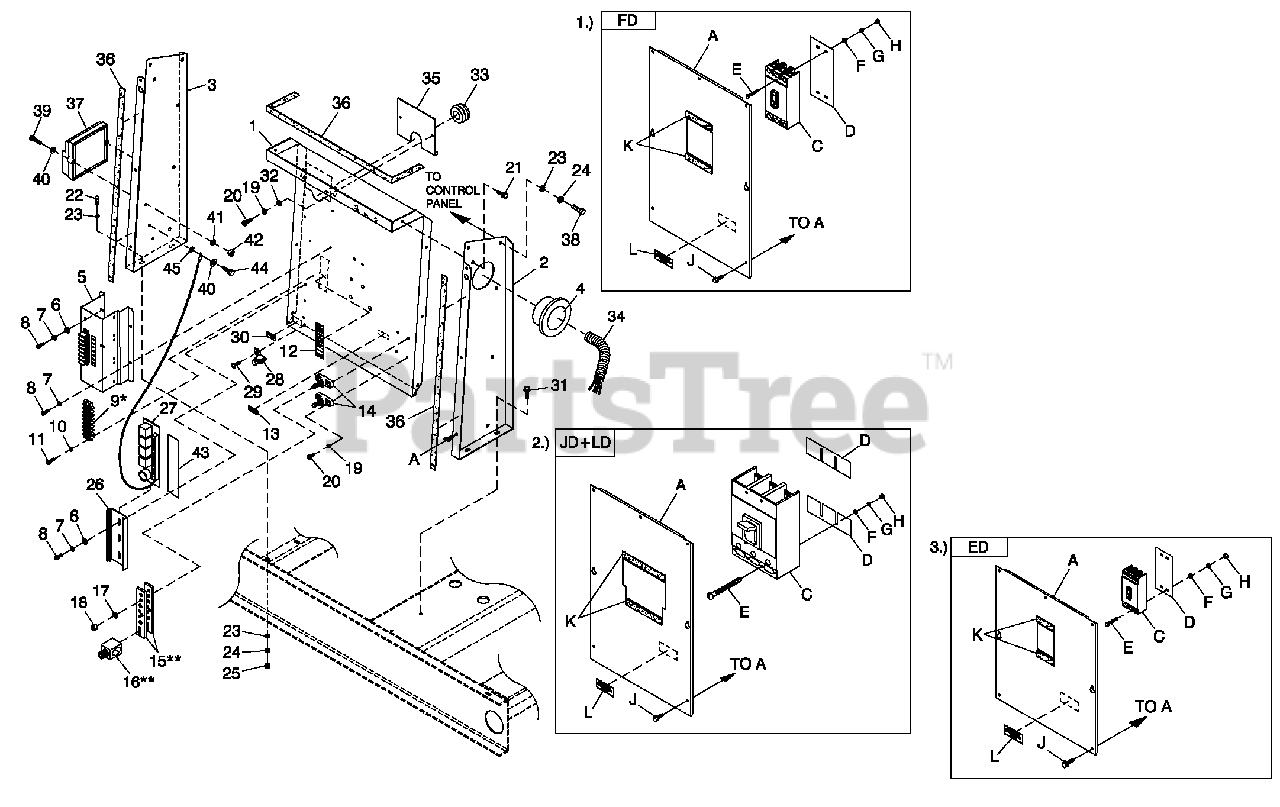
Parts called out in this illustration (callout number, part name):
1	PANEL CB CONN BOX
1	UL CIRCUIT BREAKER (FD)
2	STAND RH CONTROL
2	UL CIRCUIT BREAKER (JD+LD)
3	STAND LH CONTROL C5 GRBX
3	UL CIRCUIT BREAKER (ED)
4	BUSHING SNAP SB-2.5-31
5	INTERFACE 1PH 240V
6	WASHER FLAT M4
7	WASHER LOCK #8-M4
8	SCREW PHTT M4-0.7 X 10ZYC
9	BLOCK TERM 2 0 A 8 X 6 X 1100V
10	WASHER LOCK #6
11	SCREW PHTT #6-32 X 1/2 ZYC
12	DECAL CPL CUST CONN H CTRL
13	DECAL NEUTRAL
14	JUNCTION BLOCK 3/8-16
15	BUS BAR NEUTRAL BLOCK 390
16	LUG SLDLSS 600/250-1/0 X 1/4-28
17	WASHER LOCK 3/8
18	NUT HEX 3/8-16 STEEL
19	WASHER LOCK M5
20	SCREW PHTT M5-0.8X 16 ZYC
21	SCREW THF M6-1 X 16 N WA Z/JS
22	SCREW HHC M6-1.0X 20 G8.8
23	WASHER FLAT 1/4-M6 ZINC
24	WASHER LOCK M6-1/4
25	NUT HEXM6X 1 .0G8YELCHR
26	RAIL SNAPTRACK PCB HOLDER BULK
27	ASSY RELAY PCB 12VDC
28	LUG SLDLSS #6-14X 13/64CU
29	SCREW HHTT #10-32X3/8 CZ
30	DECAL GROUND LUG
31	SCREW HHTT M6-1.0X16ZYC
32	WASHER FLAT M5
33	GROMMET 1.25 X .25 X .75
34	CONDUIT FLEX 2.0" ID
35	PLATE WIRE SNGLGALV
36	TAPE ELEC 1/2 FOAM (AS REQ'D)
37	ASSY PCB HSB CTRL IGN MODULE
38	SCREW HHC M6-1.0X16G8.8
39	SCREW PPHM #10 /32X2
40	WASHER FLAT #10 ZINC
41	WASHER LOCK #10
42	NUT HEX #10-32 STEEL
43	DECAL H-100 RB3 CUST CONN
44	SCREW HHTT M4-0.7X 8 ZP
45	WASHER SHAKEPROOF EXT #10 STL
A	COVER FD FRM CB
C	CB 0150A 3P 600V S FD6 LL
D	INSULATOR CB FD FRAME 30MIL
E	SCREW SHC 1/4-20 X 4 G8.8 NZ
F	WASHER FLAT 1/4-M6 ZINC
G	WASHER LOCK M6-1/4
H	NUT HEX 1/4-20 STEEL
J	SCREW THF M6-1 X 16 N WA Z/JS
K	TAPE ELEC 1/2 FOAM (AS REQ'D)
L	DECAL CUSTOMER CONNECT INSIDE
A	COVER C IRBRKRJD/LD
C	CB0300A3P 600VS JD6 LL
D	INSULATOR CIRCUIT BR. JD/LD
E	SCREW RHM 1/4-20X3
A	COVER,ED CB TALL
C	CB 0090A 3P 480V S ED4 LL
D	INSULATOR CBS(ED-3P)
E	SCREW RHM #10-32X4-1/2
F	WASHER FLAT #10 ZINC
G	WASHER LOCK #10
H	NUT HEX #10-32 STEEL
